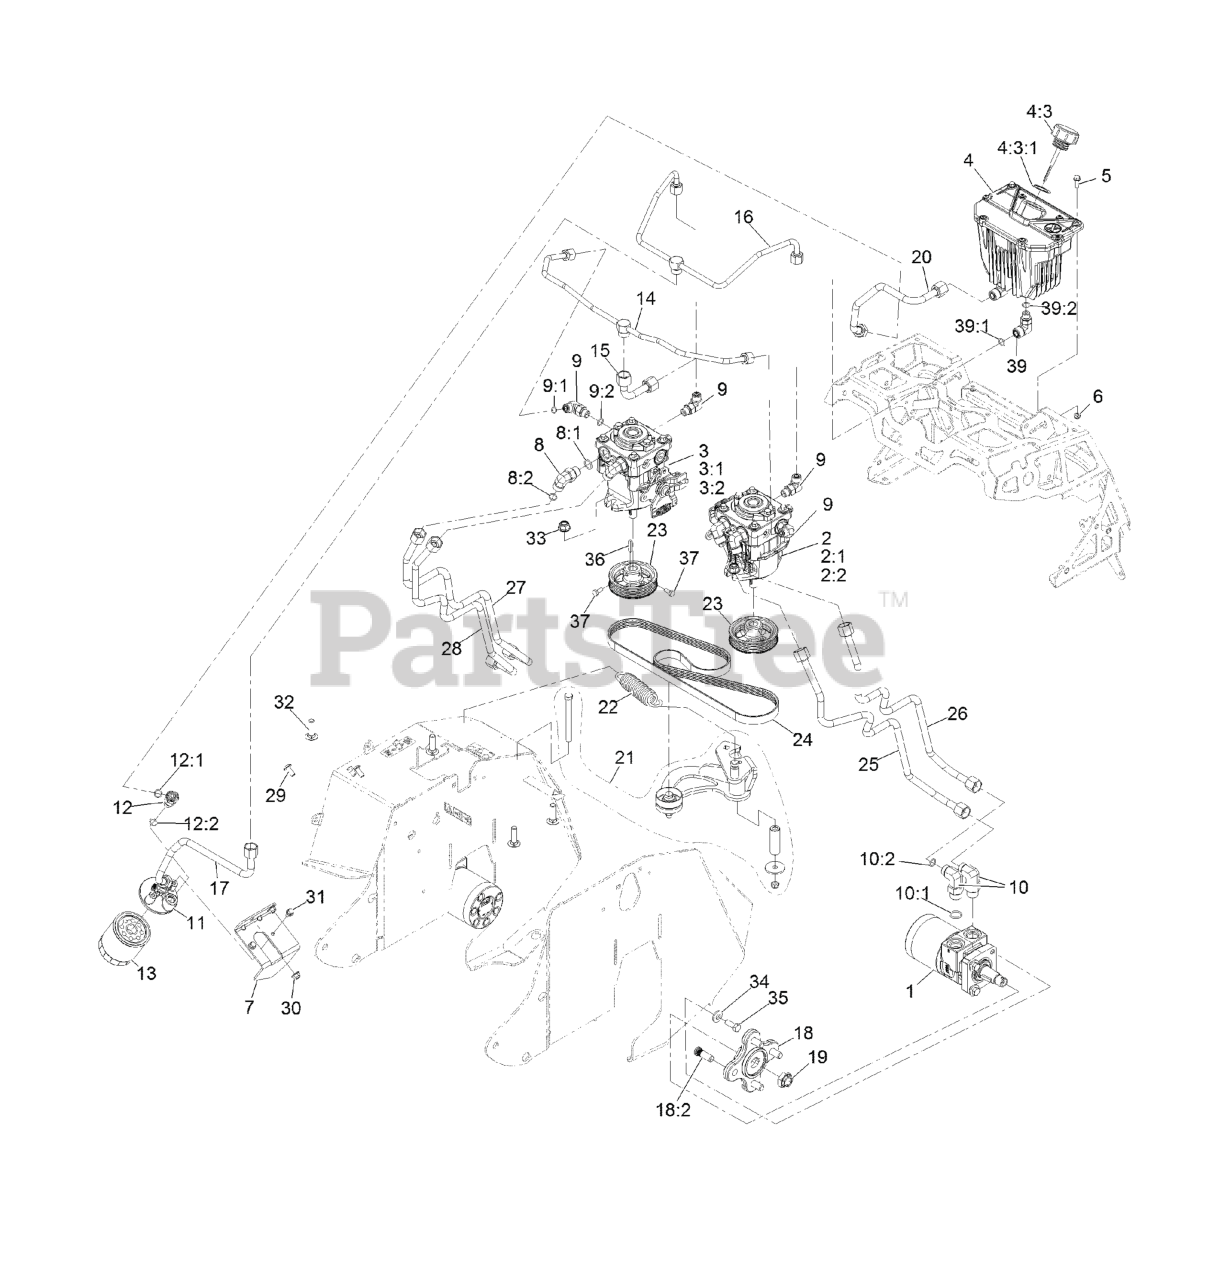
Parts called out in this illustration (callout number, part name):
1	MOTOR-WHEEL
2	PUMP-HYDRAULIC 10CC
2:1	KIT, 10CC/12CC PUMP KIT
2:2	SEAL OVERHAUL KIT
3	PUMP-HYDRAULIC 10CC
3:1	KIT, 10CC/12CC PUMP KIT
3:2	SEAL OVERHAUL KIT
4	ASM, HYDRAULIC RESERVOIR
4:3	RESERVOIR CAP ASM
4:3:1	GASKET-CAP
5	SCREW-HWH
6	NUT-LOCK, NI
7	BRACKET-FILTER
8	FITTING-ELBOW, 90 DEG
8:1	O-RING
8:2	O-RING
9	FITTING-ELBOW, 90 DEG
9:1	O-RING
9:2	O-RING
10	FITTING-ELBOW, 90 DEG
10:1	O-RING
10:2	O-RING
11	HEAD-FILTER
12	Adapter
12:1	O-RING
12:2	O-RING
13	FILTER-25 MICRON, BI-DIRECTIONAL
14	LINE, HYDRAULIC, CASE TEE
15	LINE, HYDRAULIC, CASE
16	LINE, HYDRAULIC, CHARGE TEE
17	LINE-HYDRAULIC CHARGE
18	ASM-HUB AND STUDS
18:2	STUD-WHEEL
19	NUT-LOCK
20	LINE-HYDRAULIC SUPPLY
21	ASM, IDLER ARM
22	SPRING, EXTENSION
24	BELT, PVK5
29	SCREW-TORX
30	NUT-HF, NI
31	SCREW-HHF
32	BOLT-CARR
33	NUT-HF, NI
34	WASHER-BELLEVILLE
35	SCREW-HH
36	KEY, 5MM X 5MM X 29MM
37	Screw-SQH
39	Fitting-HYD, 90 DEG
39:1	O-RING
39:2	O-RING
40	Washer-Thrust
